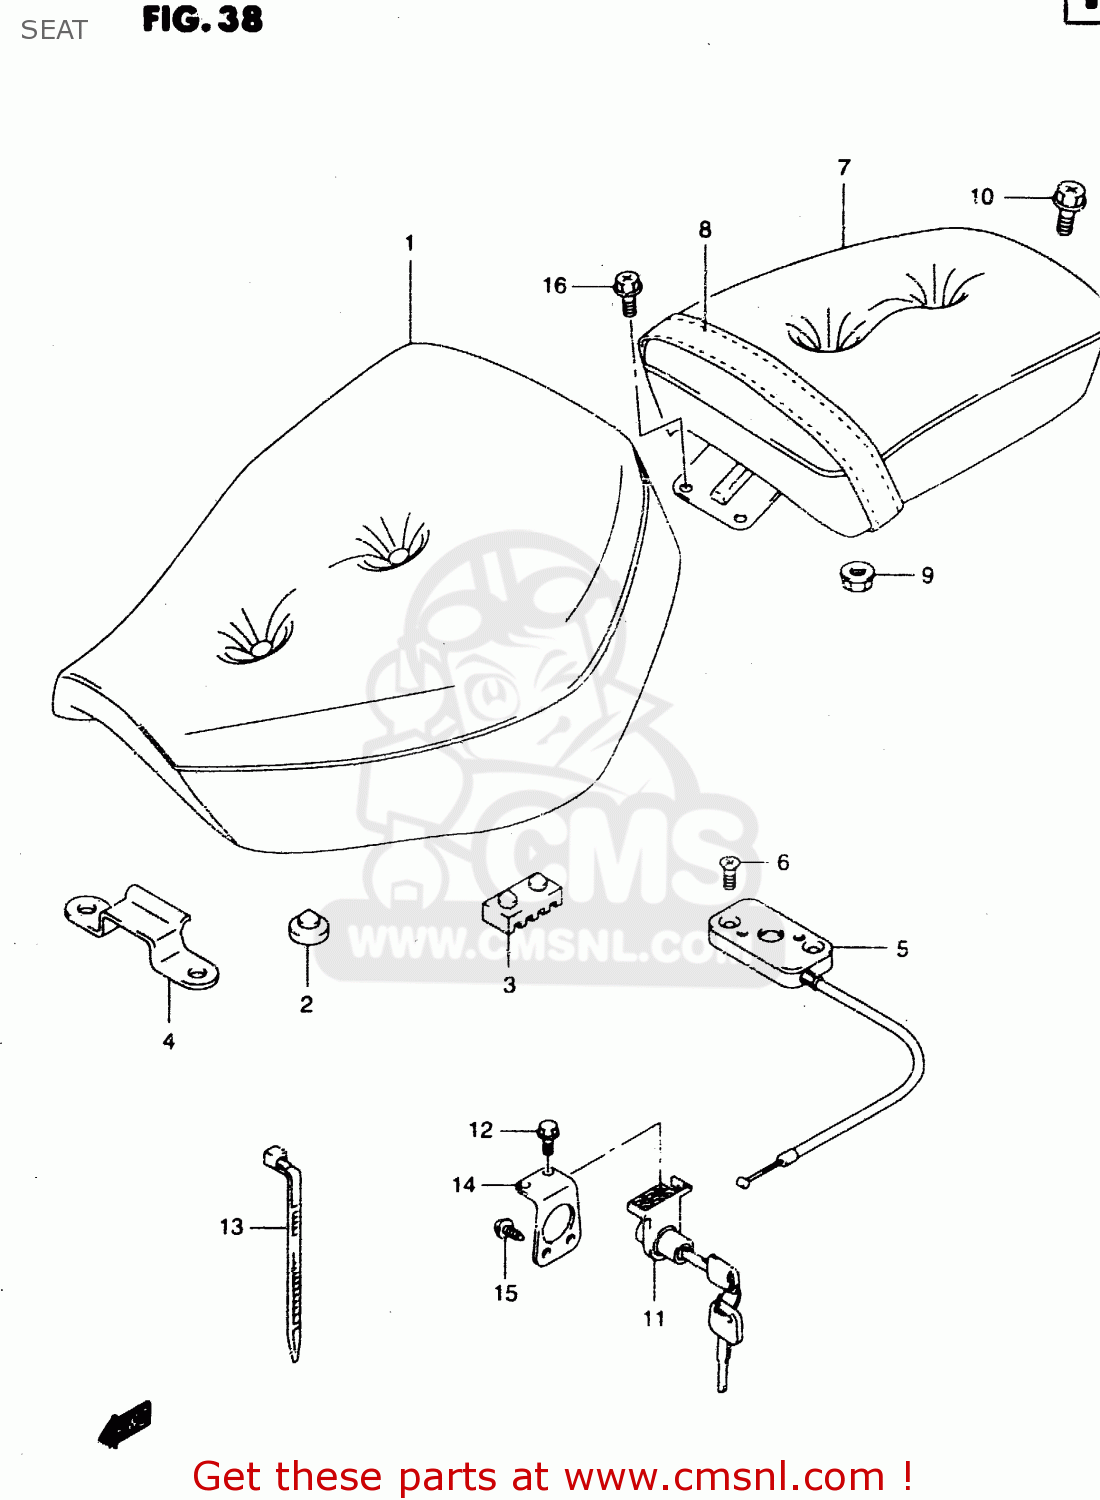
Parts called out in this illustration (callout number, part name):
1	SEAT ASSEMBLY
2	CUSHION,SEAT
3	CUSHION,SEAT(40X20X15)
4	PLATE,FR SEAT HOOK
5	BRACKET,SEAT SUPPORT
6	SCREW
7	SEAT ASSEMBLY,PILLION
8	BAND,SEAT(BLACK)
9	NUT
10	BOLT(8X16)
11	LOCK SET,SEAT
12	BOLT
13	CLAMP(L:220)
14	BRACKET,SEAT LOCK
15	SCREW
16	BOLT(6X12)
